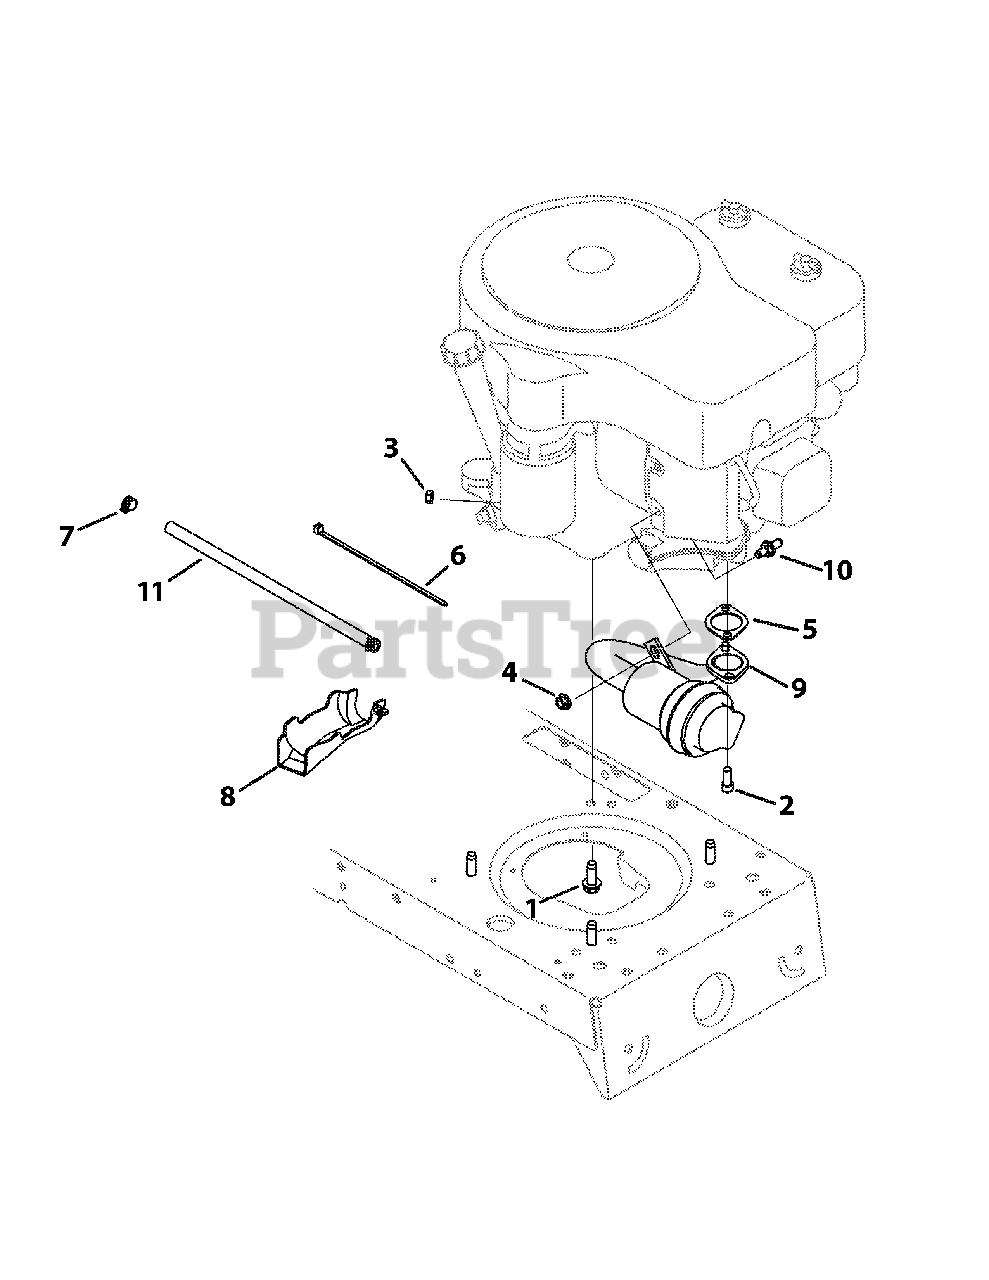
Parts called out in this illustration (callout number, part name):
1	Screw, 3/8-16 x 1.0
2	Socket Screw, 5/16-18 x .750
3	Sems Nut, 1/4-20
4	Flangelock Nut, 5/16-18
5	Exhaust Gasket, 10 HP Briggs
6	Cable Tie
7	Clamp Hose, .490 diameter
8	Oil Drain Sleeve
9	Muffler
10	Stud, 5/16-18
11	Fuel Hose, Low Permeation
